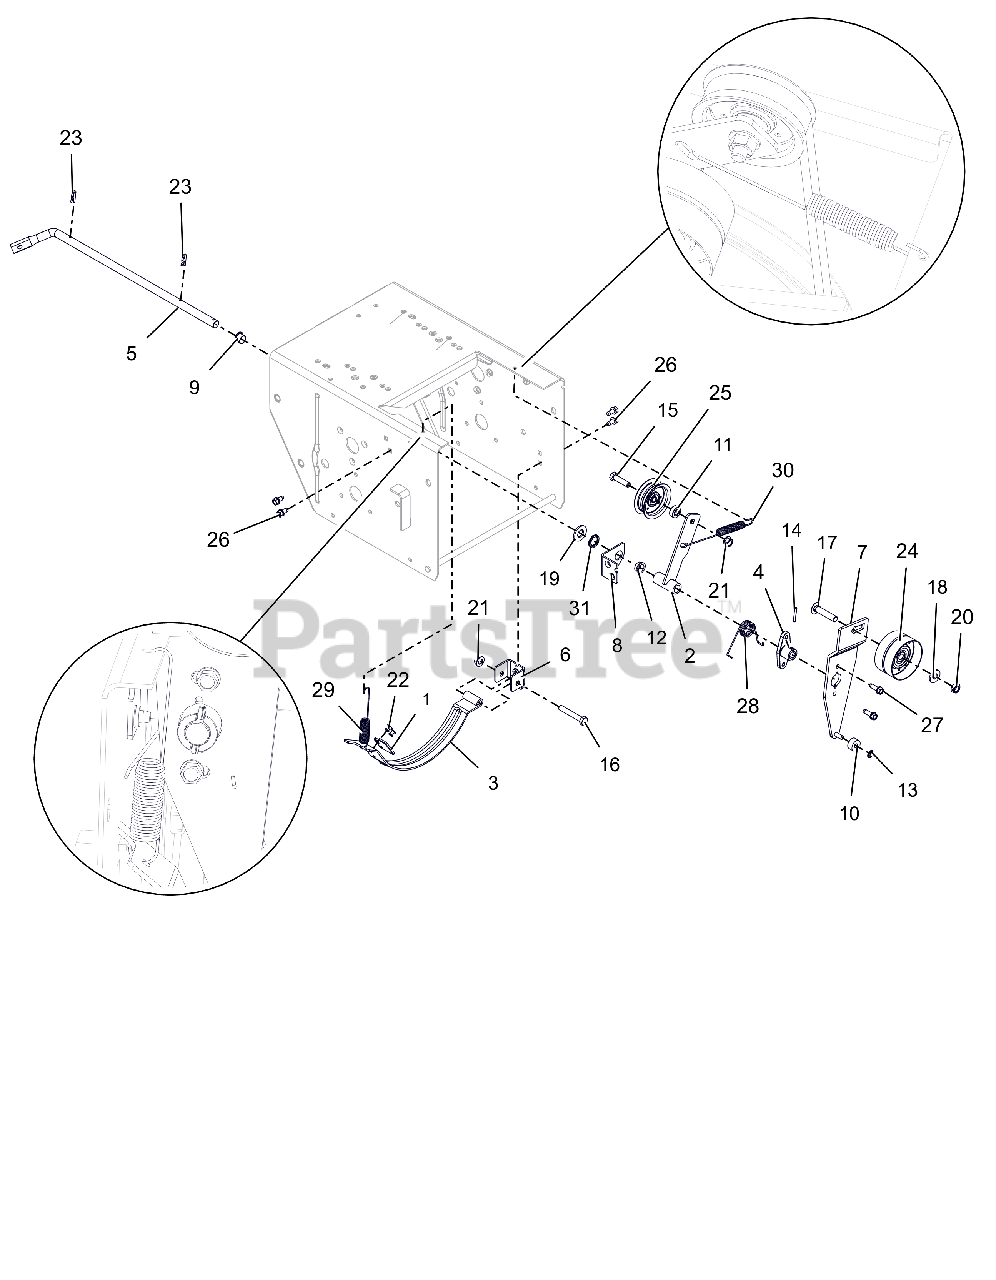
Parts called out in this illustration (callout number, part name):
1	PAD, BRAKE
2	ARM, IDLER-TRACTION
3	ARM, BRAKE-ATTACHMENT
4	HUB, BRAKE ARM
5	ARM, ATTACHMENT
6	PIVOT, BRAKE
7	ARM, IDLER-ATTACHMENT
8	BRACKET, SUPPORT
9	BUSHING, POLYLINER-.50 SPLIT
10	BSHG,SLV .265 X .625 X .375
11	SPCR, BRG .315X.500X.358X.281
12	BSHG,FLANGE .500X.625X.270X.75
13	RG-RTNG-EXT .250X.010
14	PIN-ROLL .125X1.00
15	@BLT-HEX .31-18X1.25 GR5 YWZC
16	@BLT-HEX .31-18X2.00 GR5 YWZC
17	@BLT-RHDSSQNK .38-16X1.75 G5YZ
18	@WSHR-FL-STL.38X.875X.083 YWZC
19	@WSHR-FL-STL.531X1.06X.095YWZC
20	@NUT-LK-CTR-JAM .375-16 YWZC
21	@NUT-LK-TOP-FLG .31-18 YWZC
22	RVT-POP .187 YZ
23	CLIP, SPRING
24	IDLER, FLAT-2.75 OD X .375 ID
25	IDLER, FLAT - 2.00"
26	SCR-TAP .25-20X.50 HWH TR YWZ
27	SCR-TAP-PM .25-20X.75 TR YWZ
28	SG-TORS .067X.88
29	SG-TENS .056X.60X4.40
30	SG-TENS .06X.482X5.35
31	WAVE SPRING .600X.875X.25FH
